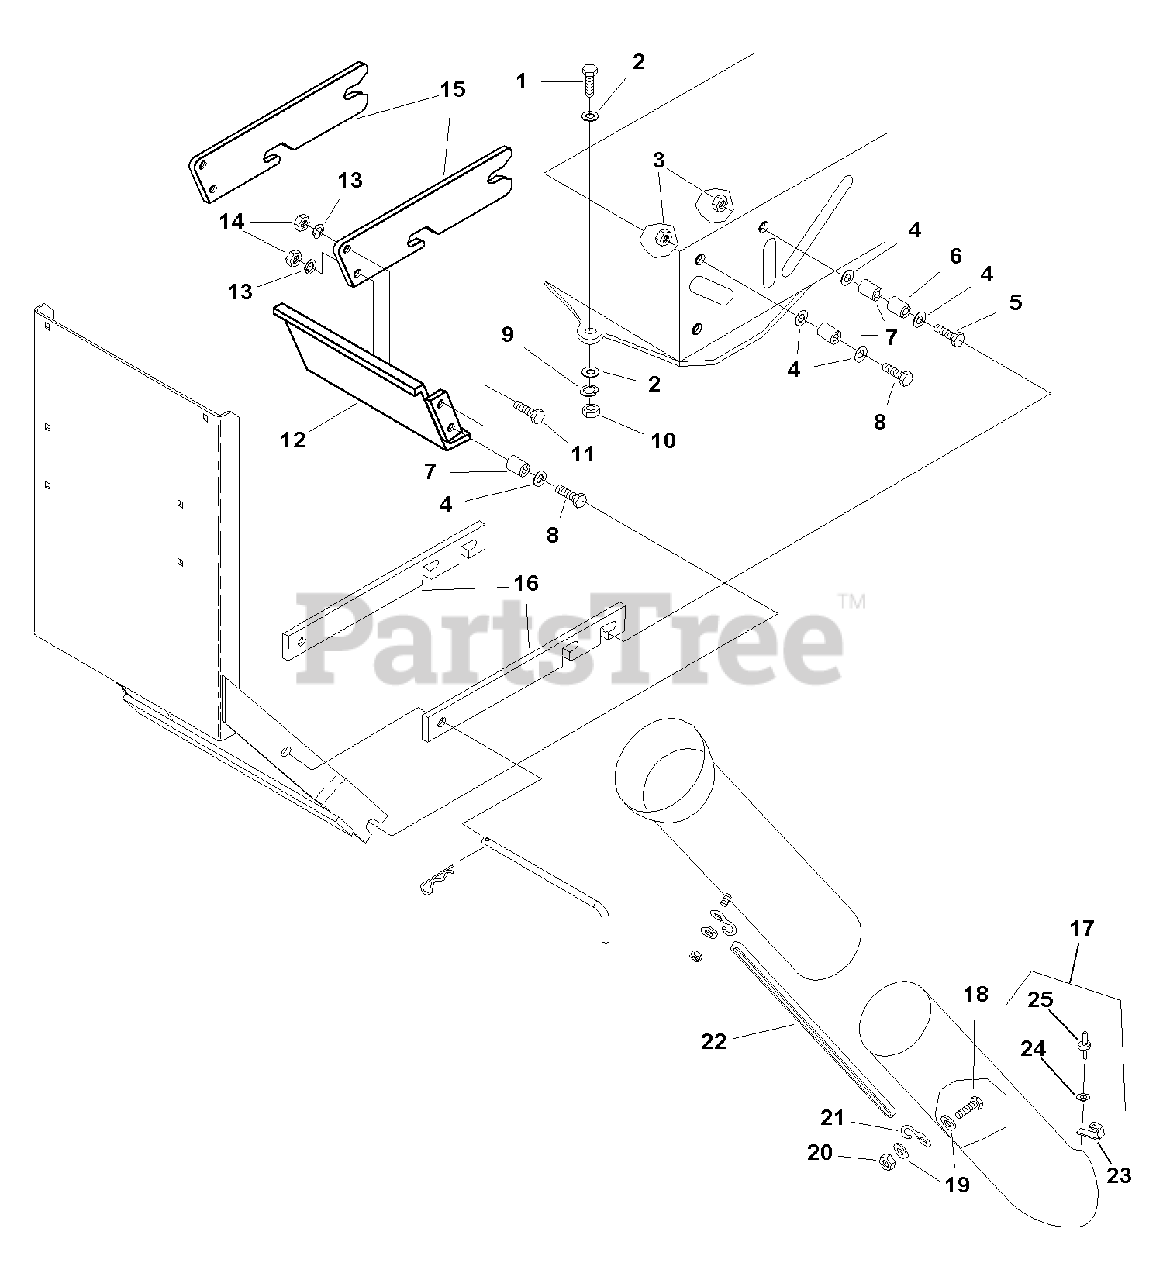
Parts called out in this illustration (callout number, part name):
1	CAPSCREW, Hex Head, 1/2-13 x 1-1/4
2	WASHER, 1/2
3	NUT, Whizlock, 3/8-16
4	WASHER, 3/8
5	CAPSCREW, Hex Head, 3/8-16 x 2
8	CAPSCREW, Hex Head, 3/8-16 x 1-3/4
9	LOCKWASHER, 1/2
10	NUT, Hex, 1/2-13
11	CAPSCREW, Hex Head, 3/8-16 x 1
13	LOCKWASHER, 3/8
14	NUT, Hex ,3/8-16
16	SUPPORT ARM
17	TUBE & CLIP ASSEMBLY
18	CAPSCREW, Hex Head 1/4-20 x 1-1/4
19	WASHER, 1/4
20	LOCKNUT, 1/4-20
23	CLIP
